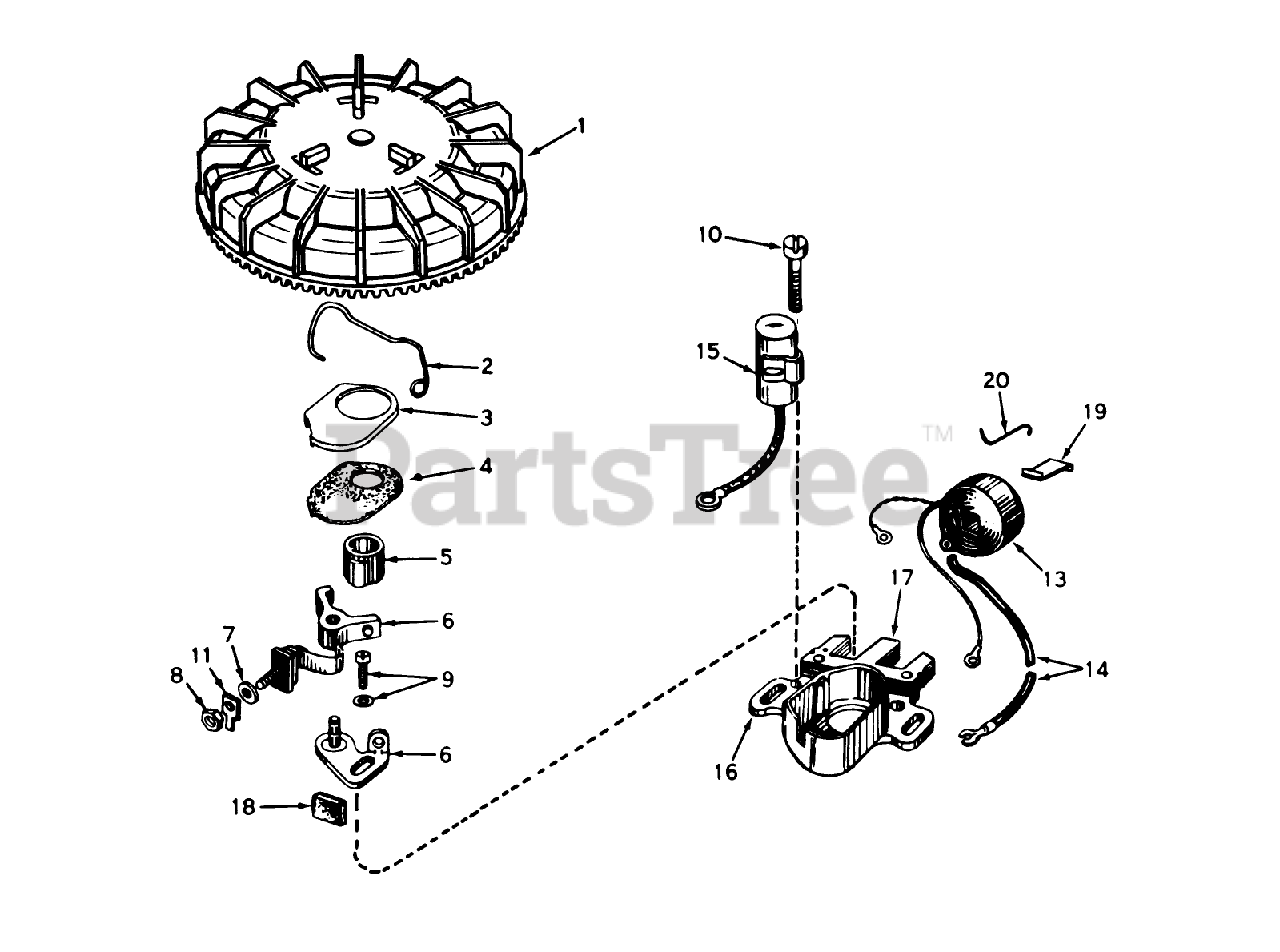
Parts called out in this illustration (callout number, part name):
1	Flywheel (Incl. Ref. #3 4)
2	Spring Breaker Box
3	Cover-Dust
4	Gasket, Dust Cover
5	Cam, Breaker
6	Breaker Assy.
7	Washer
8	DECAL
9	Breaker Screw
10	Condenser Screw
11	Terminal, Ground
13	Coil Assy. (Incl. No. 12)
14	Wire, Lead
15	Condenser
16	Core Plate
17	Stator Assy. (Incl. Ref. #2 thru 11, 13, 14, 16, 17 19)
18	Felt,Cam Wiper
19	Spring Coil Wedge
20	Clip, Coil
